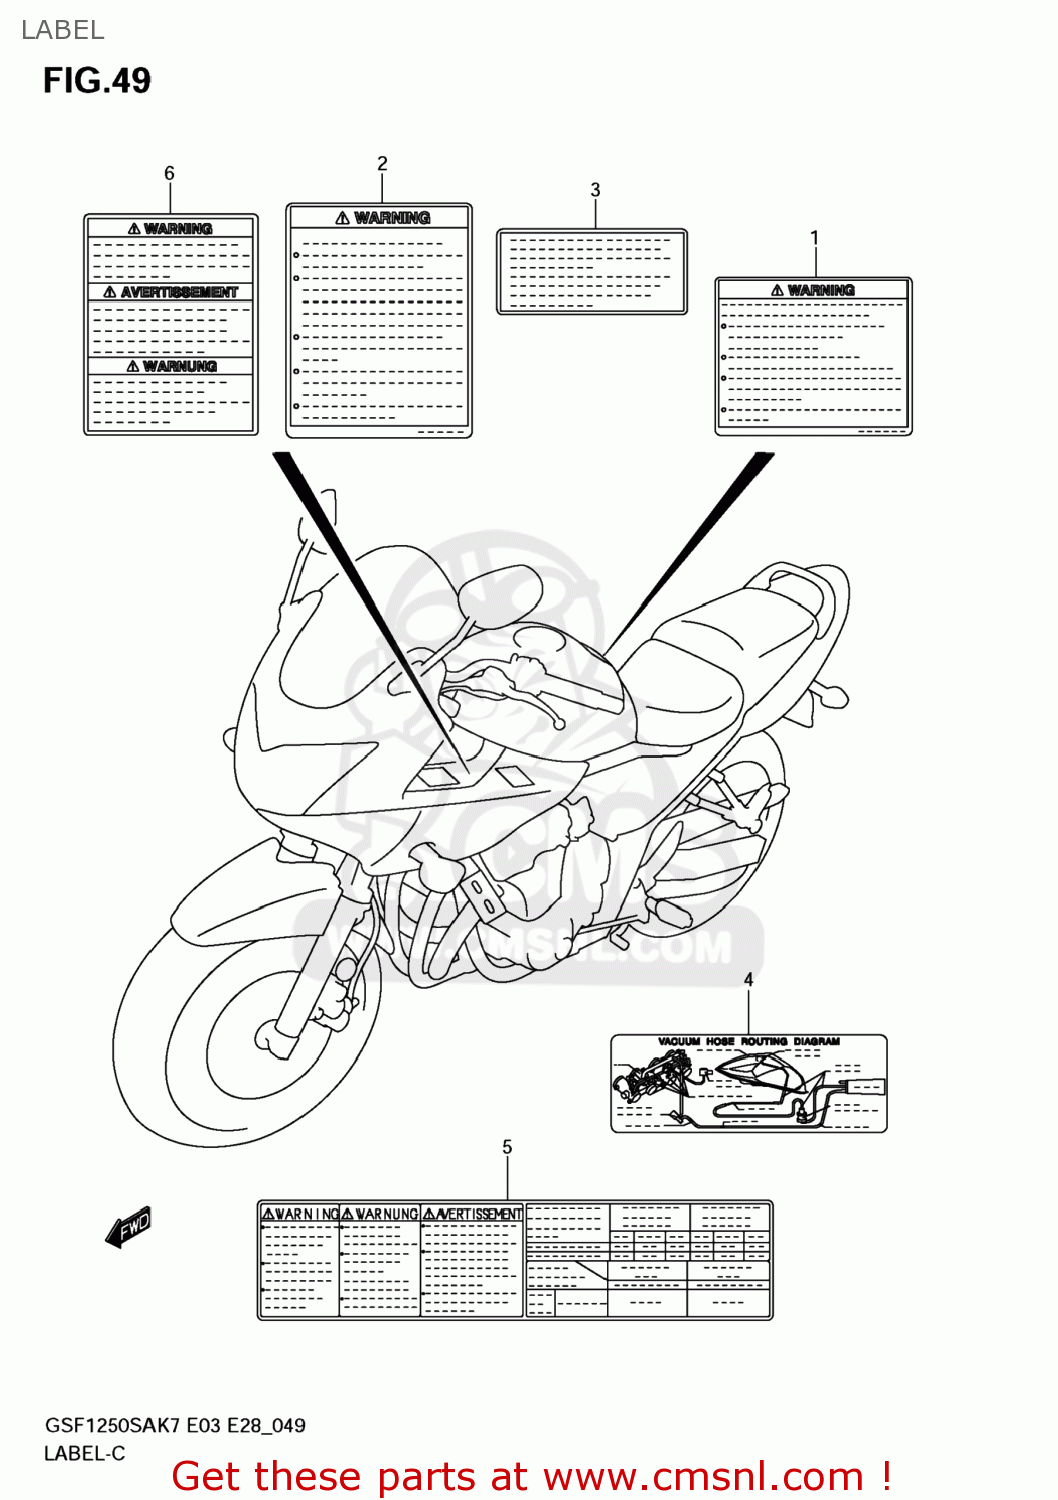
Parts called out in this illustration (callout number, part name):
1	LABEL,GENERAL WARNING
2	LABEL,SCREEN
3	LABEL,MANUAL NOTICE
4	LABEL,VACUUM HOSE ROUTING
5	LABEL,TIRE INFORMATION
6	LABEL,WARNING STEERING
7	MANUAL,OWNER'S
